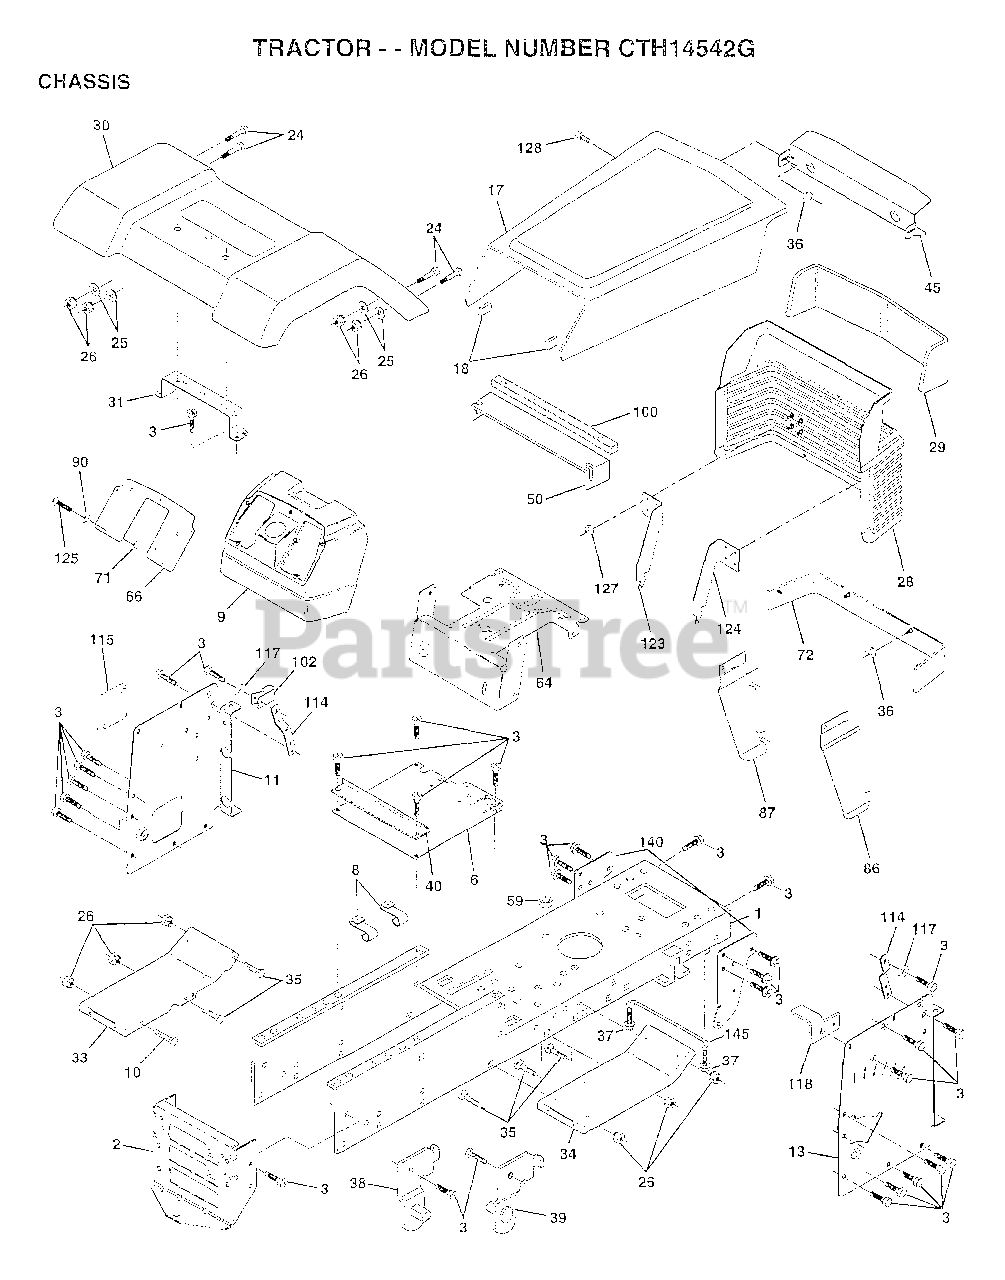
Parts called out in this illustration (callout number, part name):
3	SCREW
6	SADDLE
8	"CLIP,INSULATOR"
9	DASH.PLASTIC.BLK
11	PANEL.DASH.LH.
13	PANEL.DASH.RH.
17	HOOD/GRILLE ASM
24	BOLT
25	WASHER
26	NUT
28	GRILLE ASM WELD
31	BRACKET SUPT FEND
33	FOOTREST.LH.LT/GT
34	FOOTREST.RH.LT/GT
35	BOLT
36	PAL NUT LT
37	SCREW LT
38	BRACKET ASM LH
39	BRACKET ASM RH
40	SPACER FENDER LT
45	BEZEL.LIGHT.SLVR
50	"BAFFLE,HOOD"
64	DASH.LOWER.LT
66	PLATE SLKSCR.OM
72	STRAP FENDER ASM
86	PANEL SIDE RH ASM
87	PANEL SIDE LH ASM
90	WASHER PM
100	FOAM STRIP T
102	CLIP T
114	BRACKET.SUPT.DASH
115	COVER ACCESS
117	WASHER.SERRATED.
118	BRACKET.CLUTCH.MC
123	BRACKET.PICK.LH.
124	BRACKET.PICK.RH.
125	SCREW
127	PAL NUT
128	SCREW SPECIAL
140	BRKT SUSPENSION
145	"ROD POVOT,CHASSIS"
